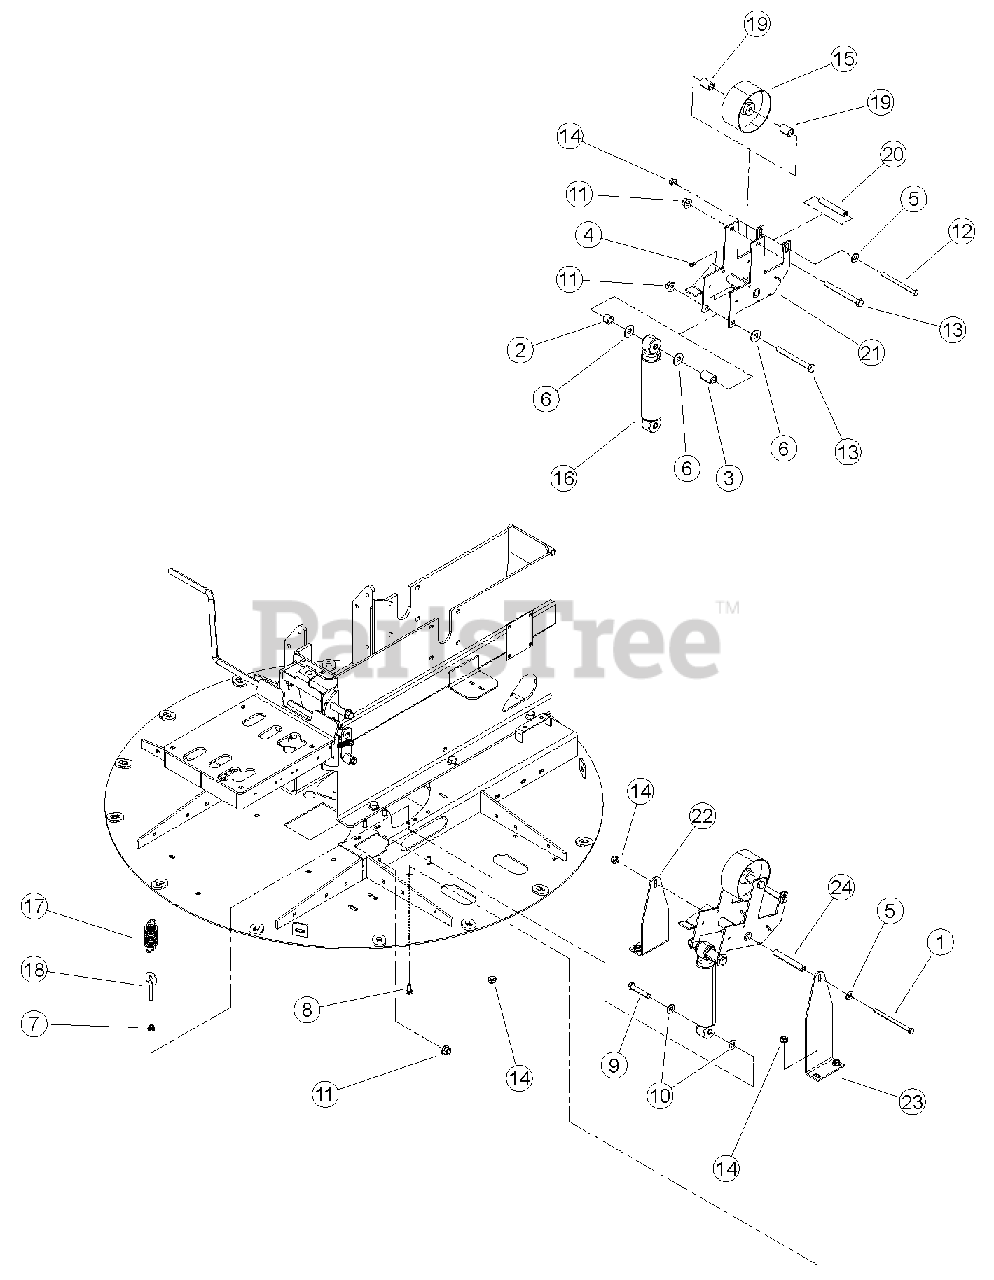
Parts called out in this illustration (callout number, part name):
1	BOLT, 3/8 X 5-1/2 HEX GR5 ZP
2	SPACER, .875 X .562 X .62 STL
3	SPACER, 1.00 X .688 X 1.50 STL
4	FITTING, 1/4 SELF-TAP GREASE
5	WASHER, 3/8" FLAT ZP
6	WASHER, 1/2" FLAT ZP
7	NUT, 3/8" SERRATED FLANGE NC ZP
8	BOLT, 3/8 X 1" GR5 CRG NC ZP
9	BOLT, 1/2 X 2-1/2 GR5 HEX CAP ZP
10	WASHER, 1/2" SAE FLAT ZP
11	NUT, 1/2-13 NYLOCK FLANGE
12	BOLT, 3/8 X 5" GR5 HEX CPS ZP
13	BOLT, 1/2 X 5" GR5 HHCS NC ZP
14	NUT, 3/8-16 NYLOCK FLANGE
15	PULLEY, IDLER 5 X 2.50"
16	ABSORBER, IDLER SHOCK
17	SPRING, 1.25 OD X 3.50 LG X .148 WD
18	EYE BOLT, 3/8 X 2" G-2 ZP
19	SPACER, .875 X 1.25
20	SPACER, 5/8 OD X 11 GA X 3.80
21	WELDMENT, BELT IDLER
22	ANGLE, IDLER BRACKET
23	ANGLE, IDLER BRACKET
24	SPACER, 5/8 OD X 11 GA X 4.30
